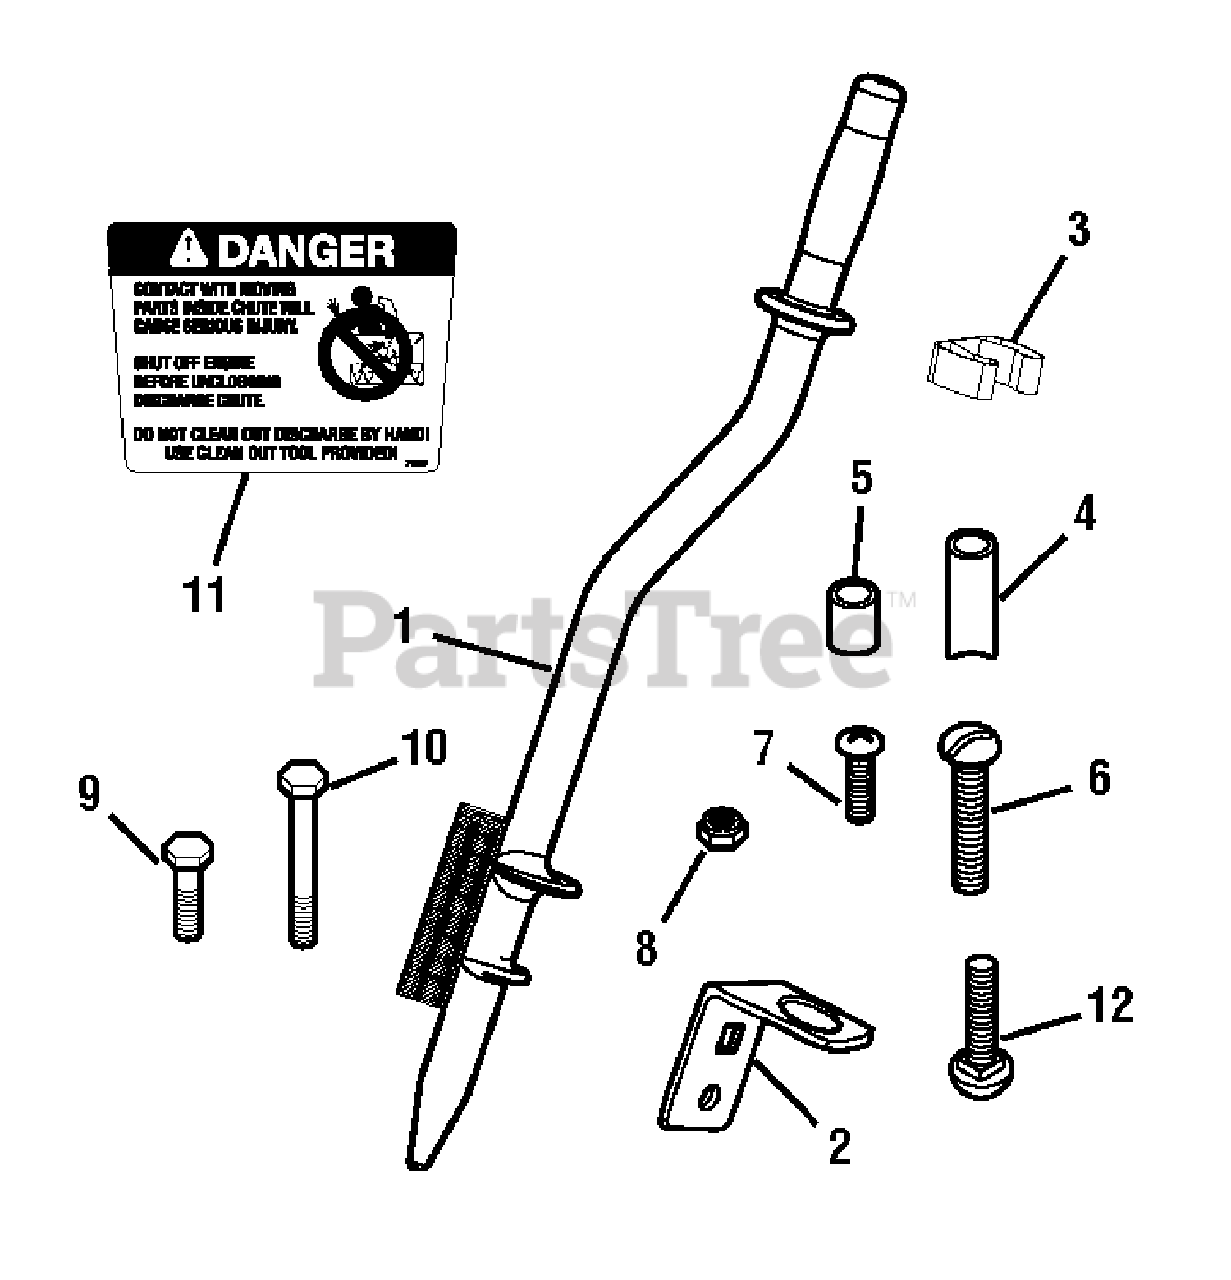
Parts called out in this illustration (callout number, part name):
1	CLEAN-OUT TOOL
2	BRACKET, Lower
3	CLIP
4	SPACER, 1-1/4 Long
5	SPACER, 11/32 Long
6	SCREW, Slotted, 10-24 x 2-1/2
7	SCREW, Phillips Head, 10-24 x 3/4
8	NUT, Nylock, 10-24
9	CAPSCREW, 5/16-18 x 1
10	CAPSCREW, 5/16-18 x 2
11	DECAL, Danger
12	Carriage Bolt, 5/16-18 x 1-3/4
